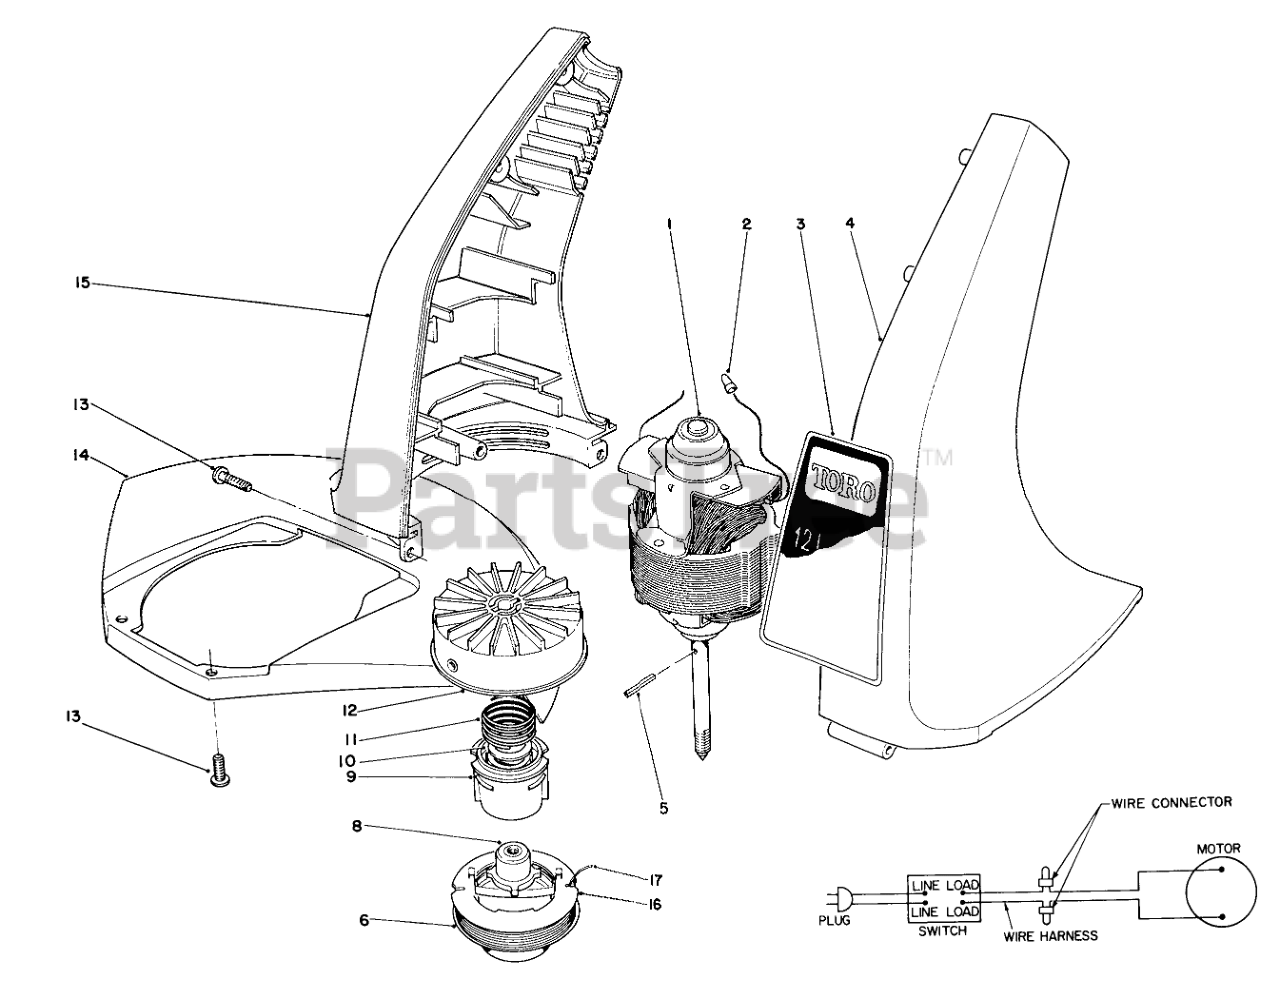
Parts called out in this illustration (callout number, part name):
1	Motor
2	CONNECTOR WIRE JOINT
3	DECAL, 12" TRIMMER
4	LH HOUSING, 12" TRIMMER
5	COIL PIN
6	Cutting Line (50 .065" Dia.)
8	DRIVER
9	SPOOL CORE
10	WASHER-FLAT
11	SPRING COMPRESSION
12	DRUM W/EYELET
13	Screw
14	SHIELD ASM-1100 W.H.RED
15	RH HOUSING, 12" TRIMMER
16	SPOOL CAP
17	LINE-FILIMENT
